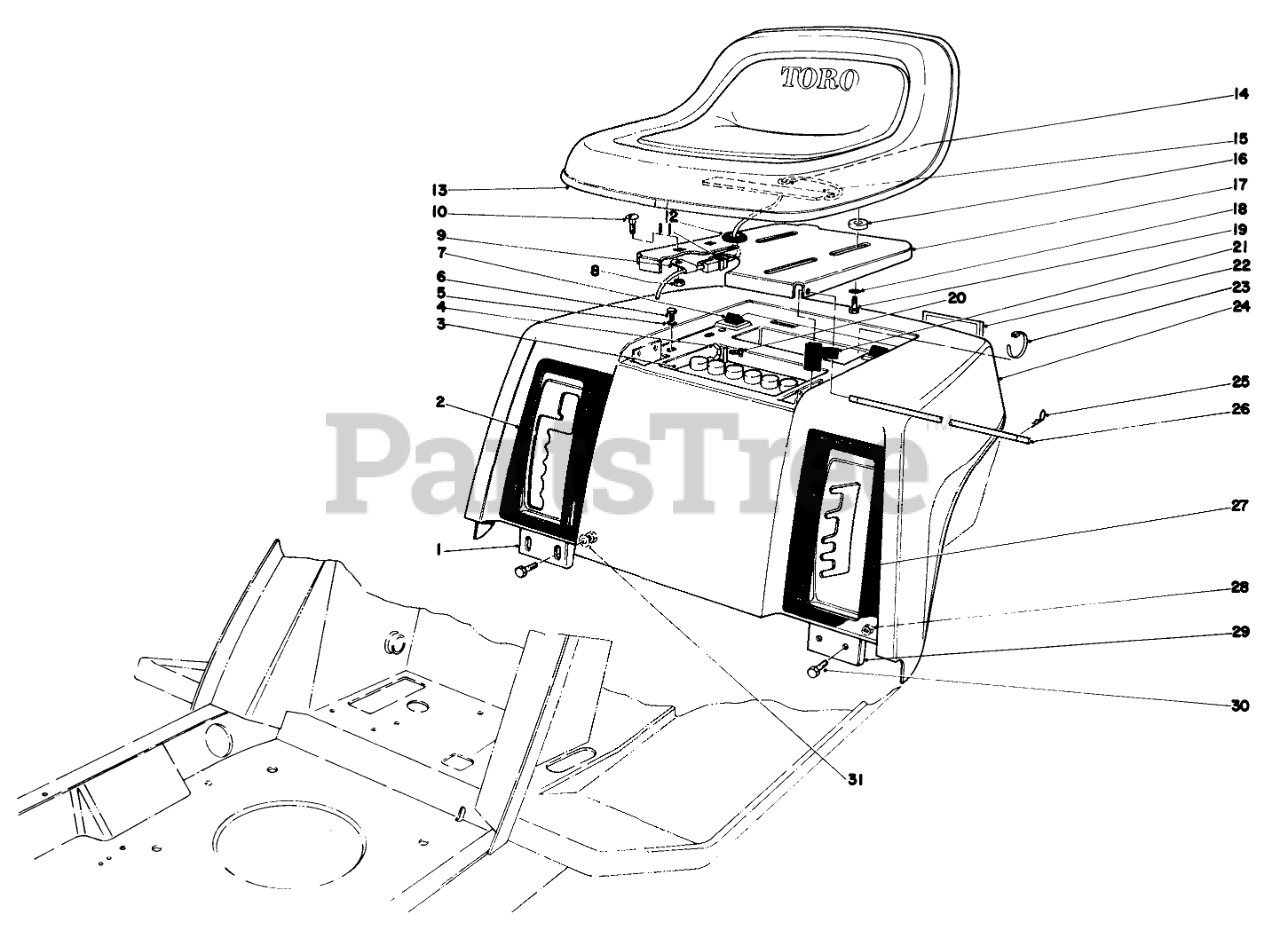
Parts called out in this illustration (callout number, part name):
1	DETENT PLATE B
2	Decal Transmission
3	Battery
4	NUT-WING
5	WASHER
6	SCREW-HWHTF
7	SEAT BUMPER
9	CLAMP
10	SCREW-CARR
11	Female Connector
12	GROMMET
13	Seat (Incl. Ref. #11 & 14-15)
14	Grommet
15	Seat Switch
16	SPACER-PIN, MOUNTING
17	SEAT SUPPORT R
18	WASHER-PLAIN
19	Screw
20	SCREW-HH
21	BOOT-TERMINAL
22	REFLECTOR
23	TIE-CABLE
24	Rear Body
25	PIN-COTTER
26	PIVOT-SEAT
27	Decal Height of Cut
28	NUT-LOCK, CONE
29	Quadrant Height of Cut
30	SCREW-HH
31	WASHER-LOCK/SP
